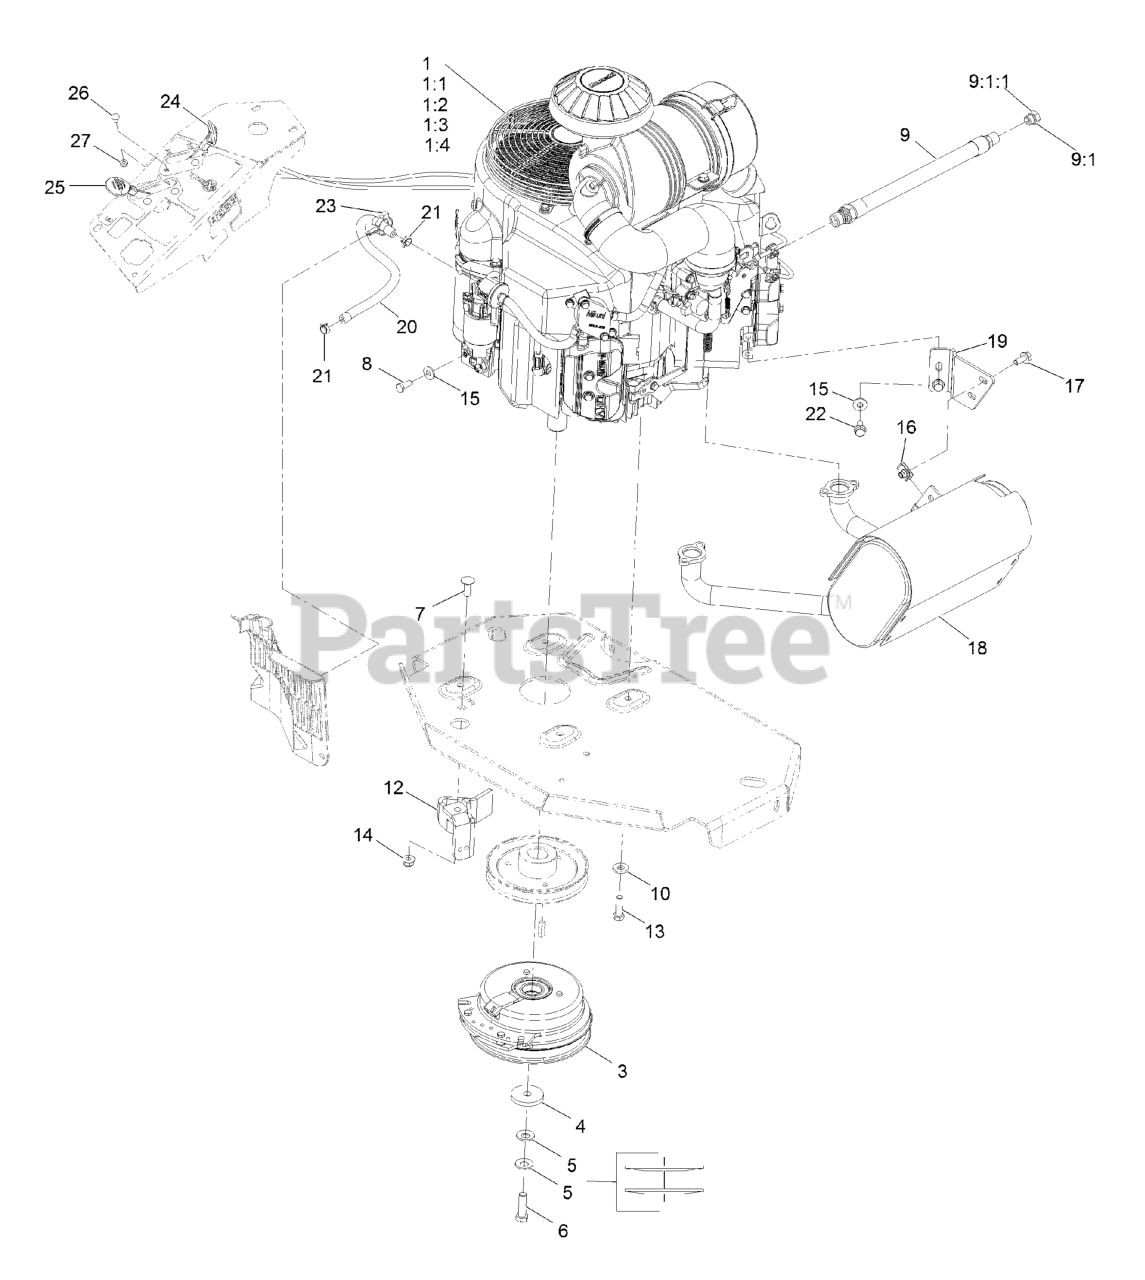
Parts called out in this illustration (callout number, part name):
1:1	Kawasaki 49065-2078 Engine Oil Filter
1:2	Kawasaki 49019-7001 Fuel Filter
1:3	Kawasaki 11013-7039 Safety Filter
1:4	Kawasaki 11013-7038 Air Filter
2	SHEAVE
3	CLUTCH KIT
4	WASHER-CLUTCH
5	WASHER-SPRING
6	SCREW-HH 7/16-20 X 1 1/2 W/LOCTITE
7	SCREW-CARR
10	SCREW-HH
11	ENGINE OIL DRAIN HOSE ASM
11:1	PLUG-HH
11:1:1	O-RING
12	WASHER-BELLEVILLE
14	CLUTCH-ANCHOR
15	SCREW-HH
16	NUT-HF, NI
17	WASHER-SPRING
19	SCREW-HHF
20	MUFFLER
21	BRACKET-MUFFLER
22	HOSE-FUEL
23	CLAMP-HOSE
24	CLAMP-HOSE
30	SCREW-HHF
